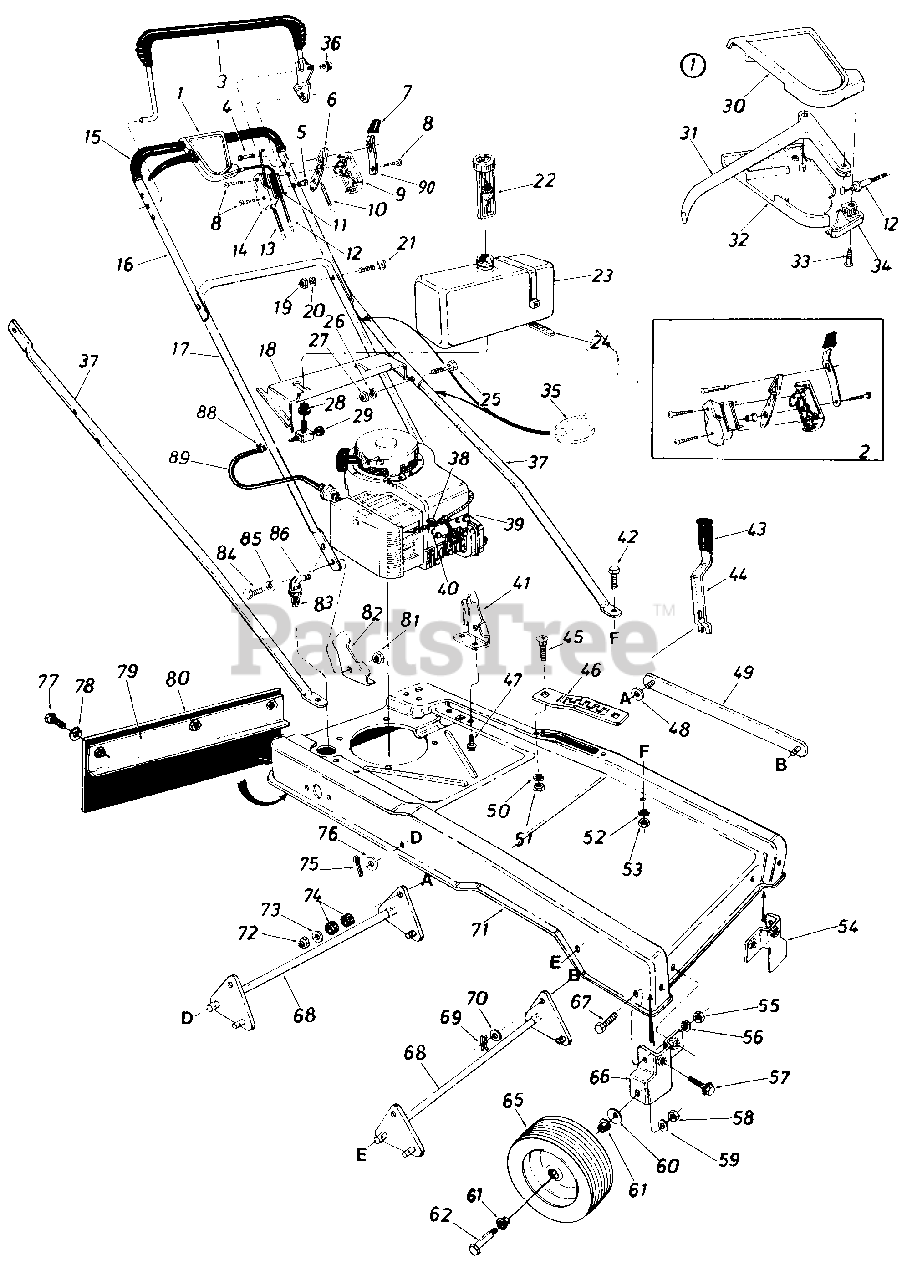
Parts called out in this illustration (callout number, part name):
1	Clutch Control Housing Comp.
2	Control Housing Comp.
3	Control Handle Ass'y.
5	Control Disc Pin
6	Throttle Control Lever
7	Spring Lever Knob
8	Truss Mach. Hi-B 0 Tap Scr. #12 x 1.50" Lg.
9	Control Panel Half
10	Throttle Control Wire 43" Lg.
11	Control Label-Throttle
12	Self-Propelled Cable 50" Lg.
13	IDrive Clutch Cable-46" Lg.
14	Clutch Panel Half
15	Grip 22" Lg.
16	Upper Handle
17	Lower Handle
18	Gas Tank Mounting Brk't.
19	Hex Nut 5/16-18 Thd.'
20	L-Wash. 5/16" I.D.
21	Carriage Bolt 5/16-18 x 1.50" Lg.
22	Gas Gauge 13/4-6 x 5.50" Lg.
24	Cable Tie 30.6" Lg.
25	Hex Bolt 5/16-24 x 1.25" Lg.
26	L-Wash. 5/16" I.D.
27	Hex Nut 5/16-24 Thd.
28	Bushing-Gas Tank
29	Fuel Shut-Off Valve w/Screen
30	Control Cover Half-Upper
31	Control Lever
32	Control Cover Half-Lower
33	Flat "C" Sunk Hd. Tap Scr. #10 x .75" Lg.
34	Cable Mounting Cap
35	Cable Tie
37	Strut .75" O.D. x 43.44" Lg.
38	Hex Sems Scr. #10-32 x .62" Lg.
39	Engine-5 H.P.
40	Casing Clamp
41	Handle Mount Brk't.-L.H.
42	Hex Bolt 5/16-18 x .75" Lg.'
44	Lift Handle
45	Carriage Bolt 5/16-18 x .62 Lg.
46	Lift Handle Support Brk't.
47	Hex Wash. Hd. B-Tap Scr. 5/16-18 x .50
48	Fl-Wash. .406" I.D x 1.25" O.D.
49	Connecting Link Ass'y.
50	L-Wash. 5/16' I.D.
51	Hex Nut 5/16-18 Thd.
52	L-Wash. 5/16" I.D.'
53	Hex Nut 5/16-18 Thd.'
54	Wheel Brk't. Ass'y.-L.H.
55	Hex Nut 5/16-18 Thd.'
56	L-Wash. 5/16" I.D.'
57	Hex Sems Bolt 5/16-18 x .75 " Lg .
58	Hex Cent. L-Nut 3/8-16 Thd.
59	L-Wash. 3/8" I.D.
60	Bell-Wash. .400" I.D. x .88"
61	Flanged Ball Brg.1/2" I.D.
62	Front Axle Bolt
66	Wheel Brk't. Ass'y.-R.H.
67	Hex Sems Bolt 5/16-18 x .75 " Lg .
68	Lift Brk't. Shaft Ass'y.
69	Intern. Cotter Pin 5/16" Dia.
70	Fl-Wash. .385" I.D. x .88" O.D.
71	Hi-Wheel Frame
72	Hex Ins. L-Nut 3/8-24 Thd.
73	Fl-Wash. .385" I.D. x .87" O.D.
74	Rubber Wash. .33" I.D. x .87" O.D.
75	Cotter Pin 1/8" Dia. x 1" Lg.
76	Fl-Wash. .510" I.D. x 1.0 O.D.
77	Hex Bolt 1/4-20 x .62" Lg.
78	L-Wash. 1/4" I.D.'
79	Retaining Strip Ass'y. 2" x 15" Lg.
80	Rear Flap 7.5 x 20" Lg.
81	Hex Nut 3/8-16 Thd.'
82	Handle Mount Brk't.
83	Part of Engine
84	Hex Bolt 3/8-16 x .75" Lg.'
85	L-Wash. 3/8" I.D.'
86	90 Deg. Elbow Male to Female 3/8
88	Hose Clamp-.406" Dia.
89	Fuel Line 15" Lg.
90	Lockout Lever
